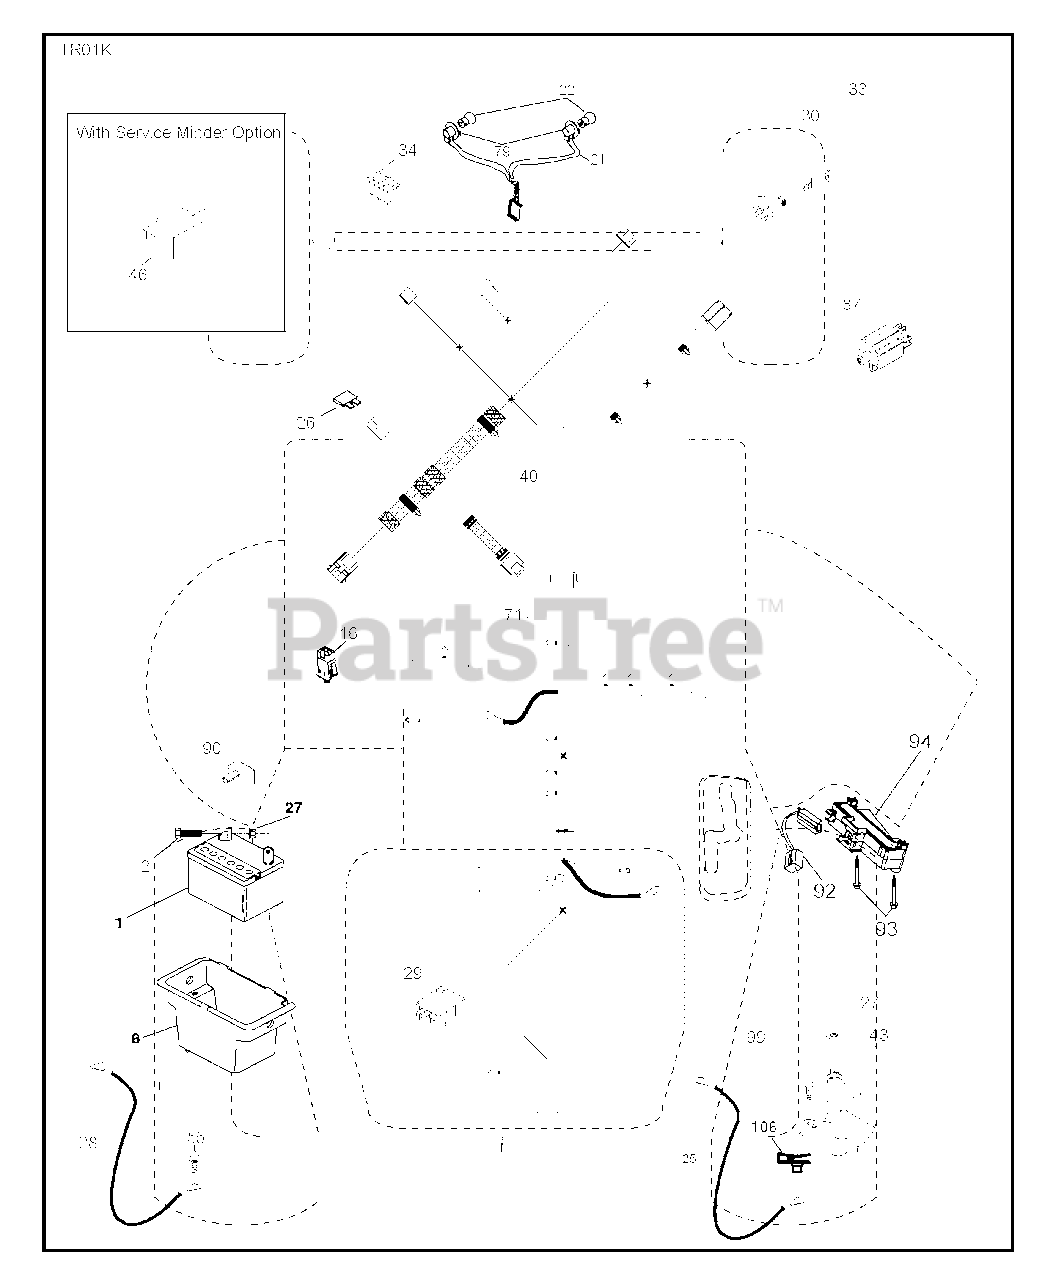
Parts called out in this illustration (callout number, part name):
1	REPL BY 532 12 38-99
2	BOLT.HEX.1/4.X.3/4.DICHROMATE
8	BOX.BATTERY.MNT.REAR.L
16	SWITCH INTERLOOK PUSH-IN
21	HARNESS.LIGHT W/4152J BULBS
22	LIGHTBULB
25	CABLE.BATT.RED.8GA.17
26	FUSE 20AMP
27	NUT
28	CABLE.GROUND.REAR.BATTERY.8G
29	SWITCH.SEAT.DP W/RAMPS
30	SWITCH.IGN.DELTA.W.LGH.ROS
33	KEY.CHAIN.BLISTER.PACK.GEN.USA
34	SWITCH LT
40	HARNESS.TEX.DASH.MAN.REAR BATT
43	SOLENOID.W/BRASS.PLUNGER
55	SCREW 5/16"
71	HARNESS.TEX.CHSSIS.REAR.BATT
79	BULB HOLDER ASM.
87	SWITCH.INTRLCK.CLUTCH.
90	COVER.TERMINAL.BATTERY
92	HARNESS.PIGTAIL.CONSLE
93	SCREW.PLASTITE
94	MODULE.REVERSE.ROS
99	SCREW HEXWSHR 1/4-20X3/4
106	1/4-20 U NUT
